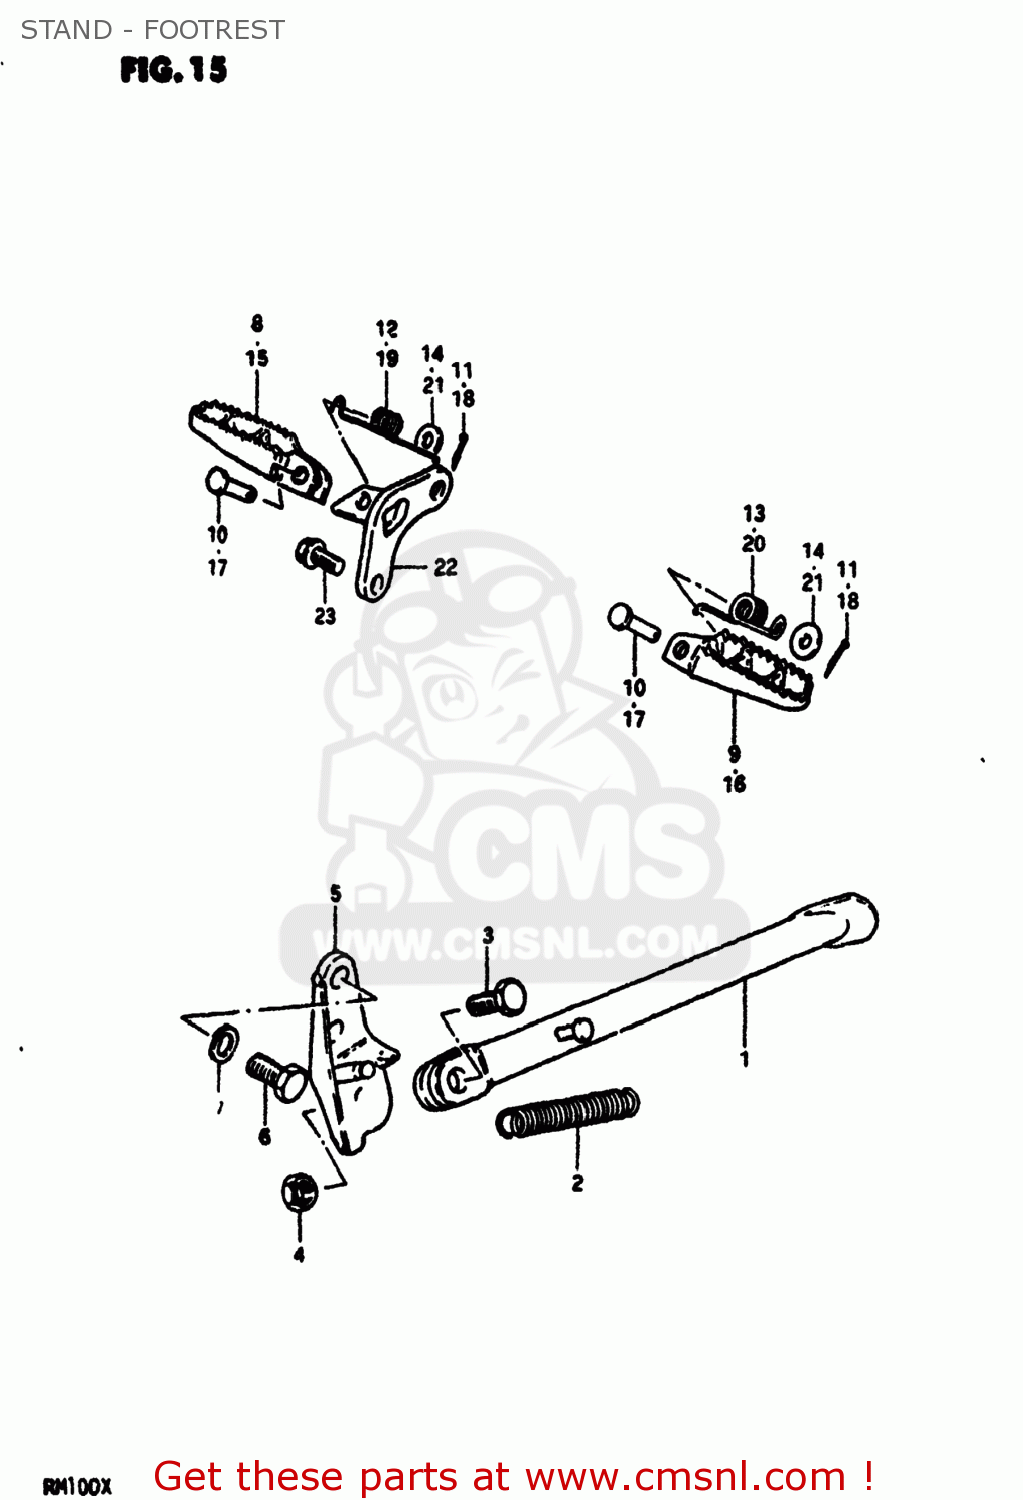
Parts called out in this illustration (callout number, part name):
1	STAND,SIDE
2	SPRING
3	BOLT(10X30)
4	NUT
5	BRACKET,PROP STAND
6	BOLT(10X19)
7	LOCK WASHER
8	RUBBER,FOOTREST
9	FOOTREST
10	PIN
11	PIN 20X20
12	SPRING
13	SPRING
14	WASHER
15	RUBBER,FRONT FOOTREST
16	FOOTREST
17	PIN
18	PIN 20X20
19	SPRING
20	SPRING
21	WASHER
22	HOLDER,FRONT FOOTREST,RIGHT
23	BOLT(10X20)
